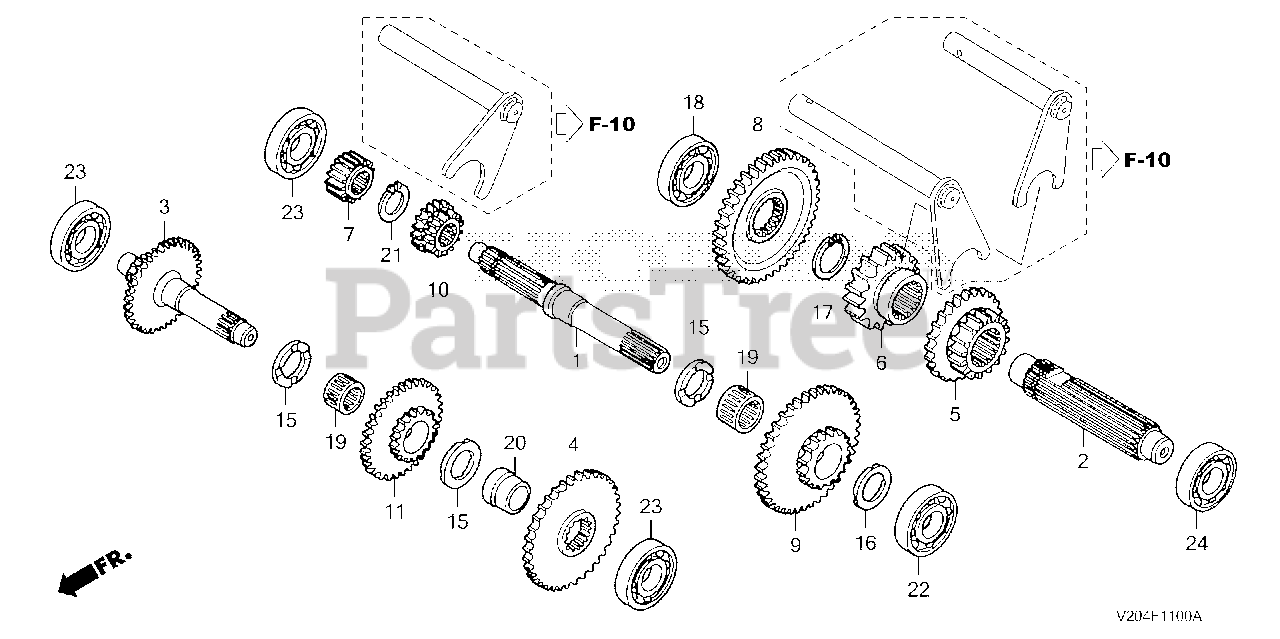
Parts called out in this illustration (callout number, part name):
1	SHAFT, INPUT
2	SHAFT, P.T.O.
3	COUNTERSHAFT, TRANSMISSION (12T/35T)
4	GEAR, COUNTER (36T)
5	GEAR, FIRST & REVERSE CHANGE (16T/24T)
6	GEAR, ROTARY CHANGE (16T)
7	GEAR, DRIVE (15T)
8	GEAR, DRIVEN (40T)
9	GEAR, FIRST IDLE (16T/39T)
10	GEAR, SECOND & THIRD CHANGE (15T/17T)
11	GEAR, COUNTER IDLE (18T/37T)
15	WASHER, THRUST (20MM)
16	WASHER, THRUST (17MM)
17	CIRCLIP (OUTER) (22MM) (NOT AVAILABLE)
18	BEARING, BALL (20X56X16)
19	BEARING, NEEDLE (20X24X17)
20	COLLAR, COUNTER GEAR
21	CIRCLIP (OUTER) (20MM)
22	BEARING, RADIAL BALL (6203)
23	BEARING, RADIAL BALL (6302)
24	BEARING, RADIAL BALL (6303)
